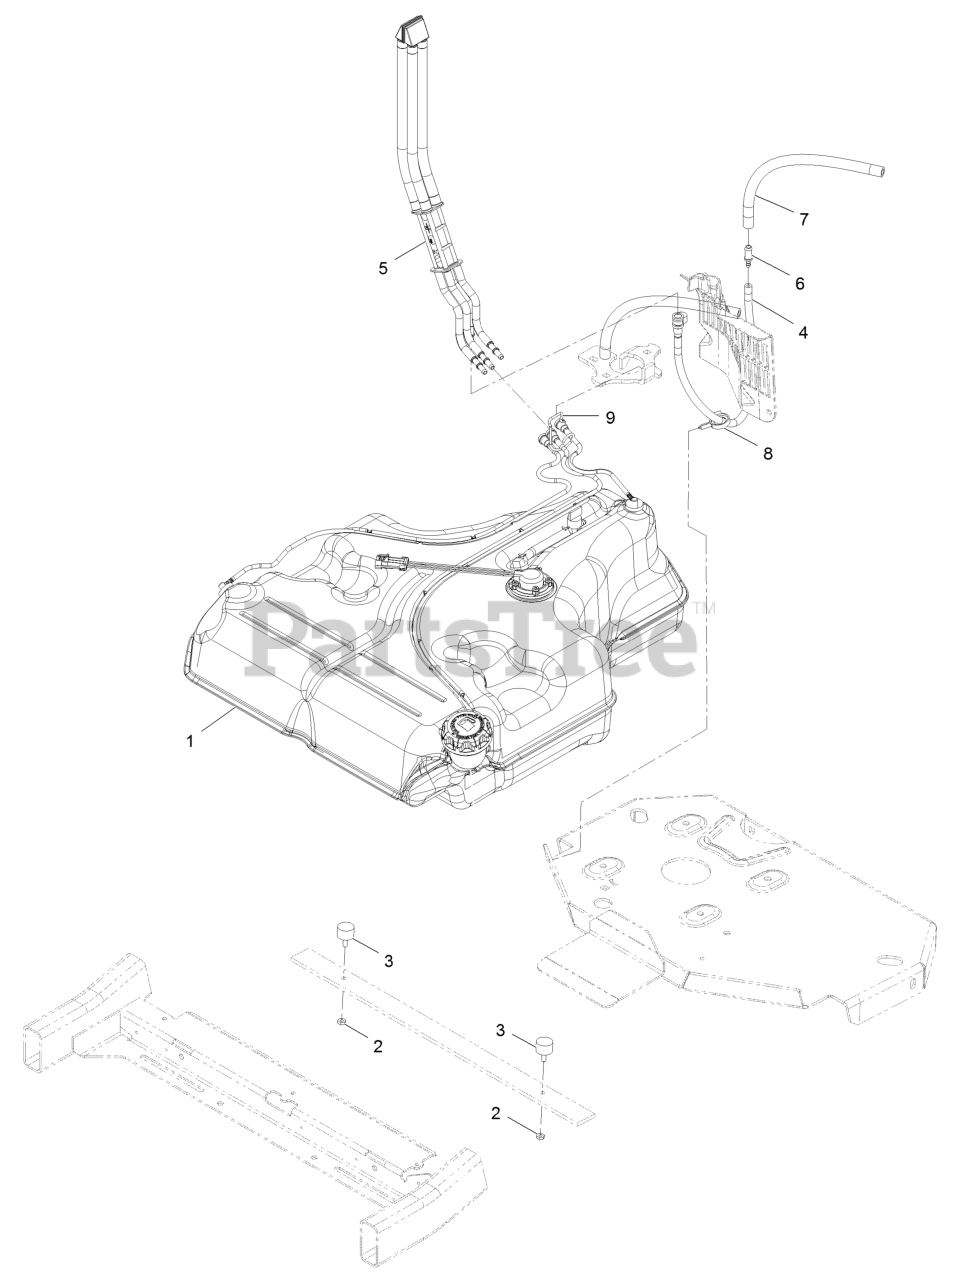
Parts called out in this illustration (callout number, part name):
2	BUSHING
3	FUEL LINE KIT (WITH GROMMET)
3:1	BUSHING
4	SCREW-PAN
5	WASHER-LOCK
6:1	GASKET-SENDER, FUEL
7	CAP-FUEL, RATCHETING
8	RH VENT LINE KIT (WITH GROMMET)
9	LH VENT LINE KIT (WITH GROMMET)
10	REAR VENT LINE KIT (WITH GROMMET)
11	VALVE-FUEL
12	CLAMP-HOSE
13	HOSE-FUEL
